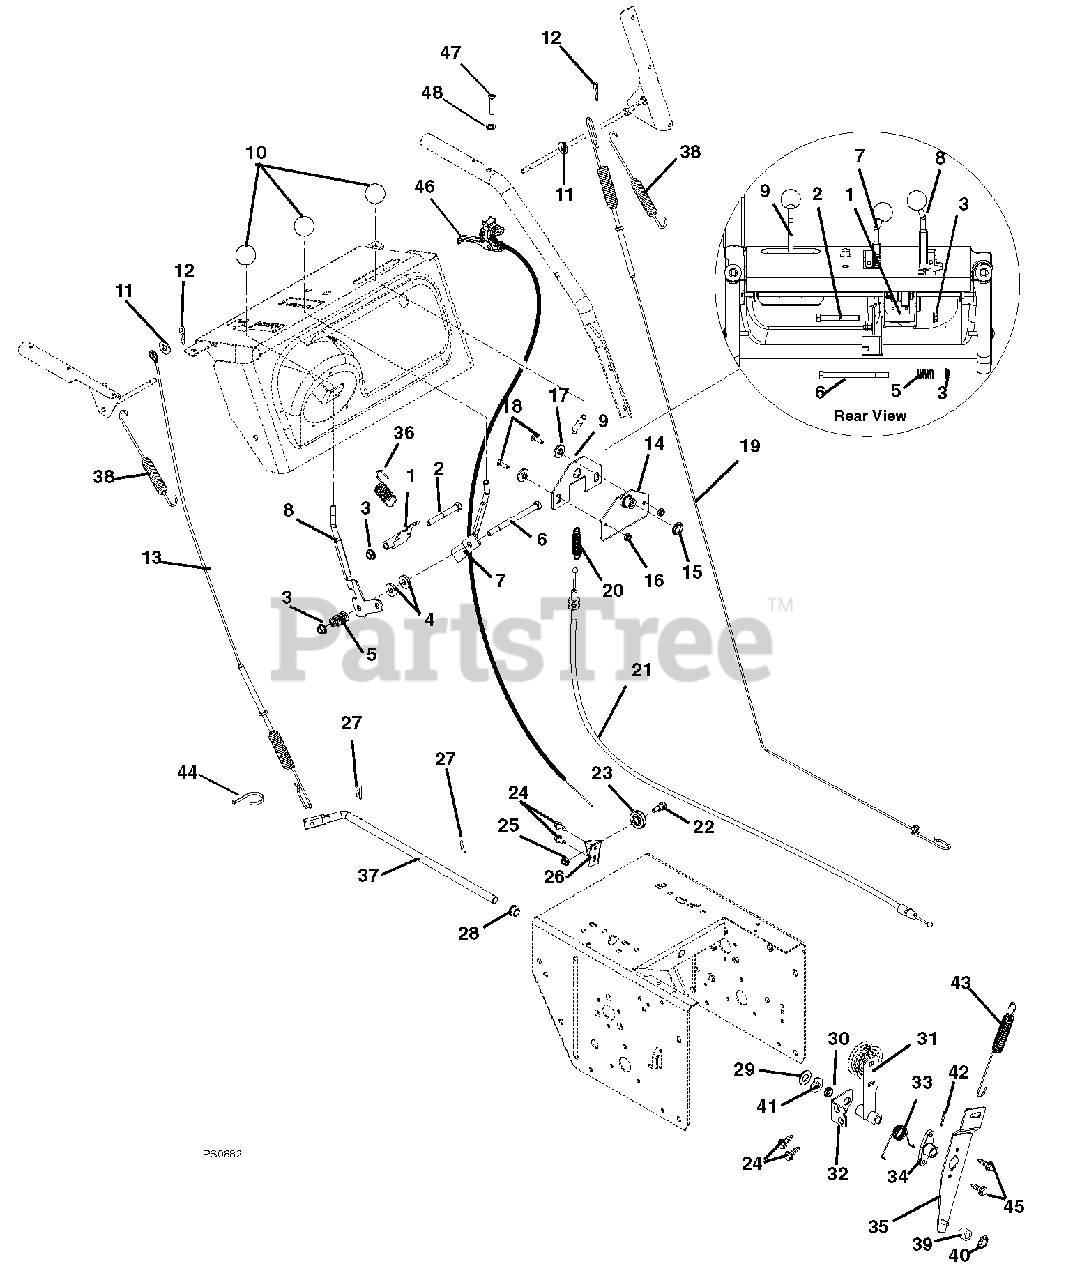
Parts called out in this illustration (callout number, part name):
1	ARM, INTERLOCK
2	@BLT-HEX .38-16X3.00 GR5 YWZC
3	@NUT-LK-TOP-FLG .38-16 YWZC
4	WSHR-FL-STL .406X1.00X.188 YWZ
5	SG-COMP .125X.781X1.250
6	@BLT-HEX .38-16X5.00 GR5 YWZC
7	CONTROL, DEFLECTOR
8	LEVER, SHIFT
9	LEVER, CHUTE CONTROL
10	KNOB,BALL -BLACK 1.47" .375-16
11	@WSHR-FL-STL.281X.62X.065 YWZC
12	PIN-HAIR INT .06X.18X.77
13	CABLE, ATTACHMENT
14	MOUNT, CHUTE CONTROL
15	BUSHING, POLYLINER-.75 SNAPIN
16	@NUT-LK-TOP-FLG .25-20 YWZC
17	BSHG-FLG .265X.448X.243X1.00
18	@BLT-HEX .25-20X.75 GR5 YWZC
19	CABLE, TRACTION
20	SG-TENS .048X.44X1.75 WLD 9
21	CABLE, CHUTE LOCK
22	BOLT, SHLDR-.375X.375X.25-20
23	PULLEY, CABLE
24	SCR-TAP .25-20X.50 HWH TR YWZ
25	@NUT-LK-TOP-FLG .25-20 YWZC
26	BRACKET, CABLE PULLEY
27	CLIP, SPRING
28	BUSHING, POLYLINER-.50 SPLIT
29	@WSHR-FL-STL.531X1.06X.095YWZC
30	BUSHING, POLYLINER-.50 SNAPIN
31	ARM, IDLER-TRACTION
32	BRACKET, SUPPORT
33	SG-TORS .067X.88
34	HUB, BRAKE ARM
35	ARM, IDLER-ATTACHMENT
36	SPRING-EXT .047X.438X1.45
37	ARM, ATTACHMENT
38	SG-TENS .056X.60X4.40
39	BSHG,SLV .270 X .750 X .250
40	RG-RTNG-EXT .250X.010
41	WAVE WASHER .531X.781X.125FH
42	PIN-ROLL .125X1.00
43	SG-TENS .06X.482X5.35
44	CABLE TIE LG 5-1/2
45	SCR-TAP .25-20X.75 HWH TR YWZ
46	CABLE, TRIGGER-REMOTE WHEEL
47	SCR-MCH .25-20X1.50 OVAL HD
48	WSHR-LK-INT .250 TH TYA
